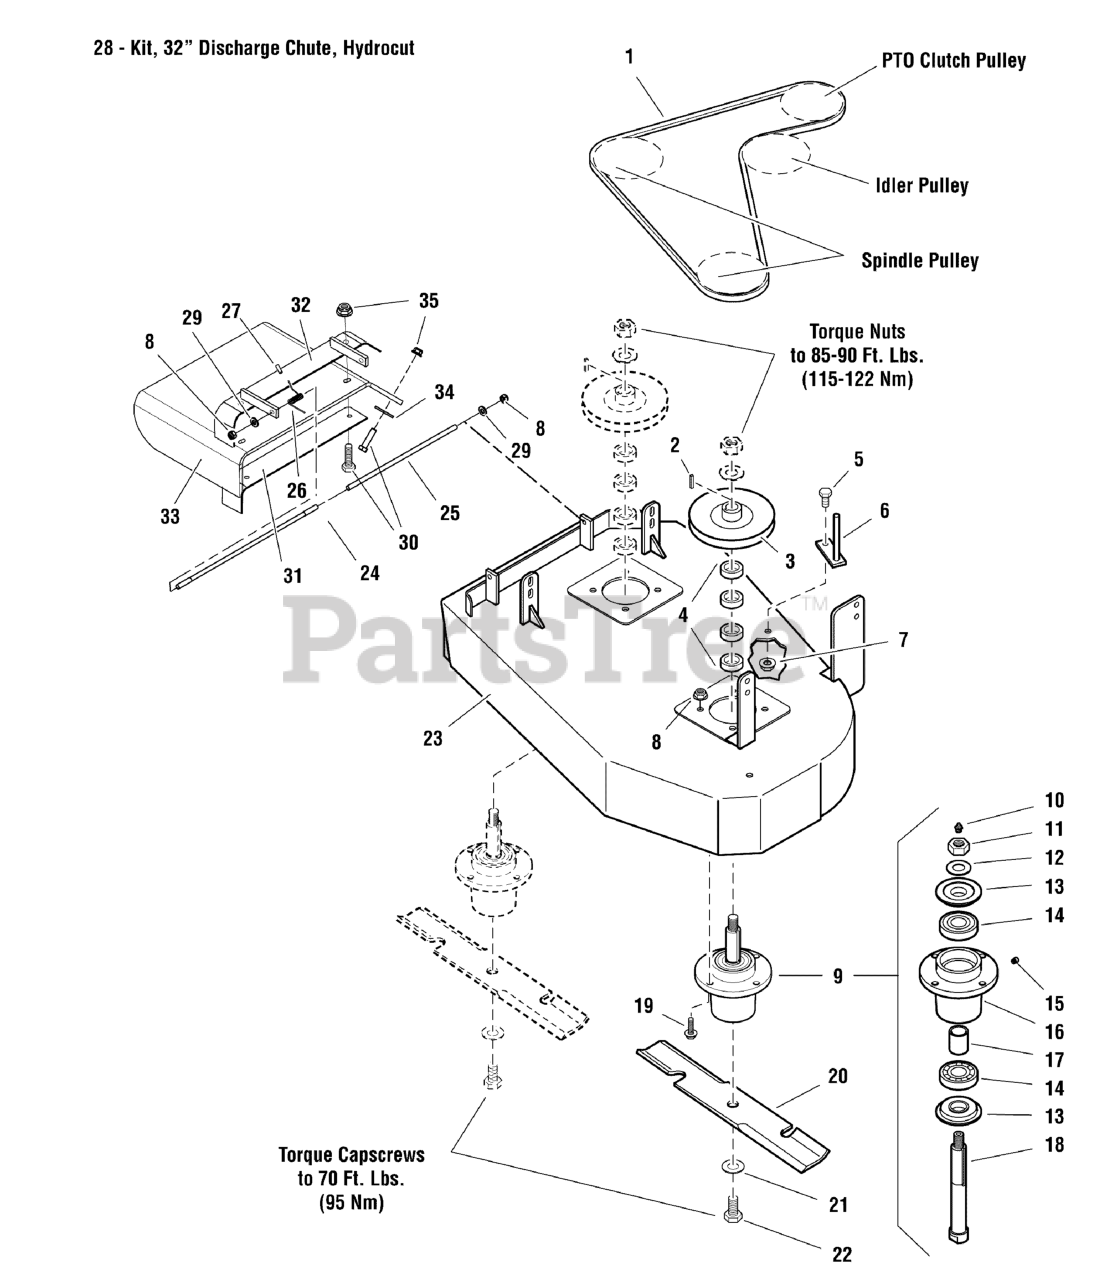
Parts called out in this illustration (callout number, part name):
1	BELT
2	KEY, 1/4 SQ. X 1
3	SPINDLE PULLEY
4	SPACER, 1.02 X 1.56 X .50
5	BOLT, 3/8-16 X 1" GD5 CZ
7	NUT, 1/4-20 HEX SERR. FLANGE
8	NUT, 5/16-18 Hex Nylock Flange
9	SPINDLE ASSM, ALUMINUM, LONG SHAFT
10	GREASE FITTING
11	NUT, 3/4-16 Hex
12	WASHER, 3/4" Belleville
13	TRASH SHIELD
14	BEARING
15	RELIEF VALVE
16	SPINDLE HOUSING
17	SPACER, 1.00 X 1.25 X 1.75
18	SPINDLE SHAFT
19	BOLT, Flange Head, 5/16-18 x 1-1/4
20	MOWER BLADE, 16-1/4"
21	WASHER, BLADE BOLT, 9/16" F436, CZ
22	BOLT, 5/8-11 x 1-3/4
23	WELD, MOWER DECK, 32" - RED
24	ROD, CHUTE PIVOT
25	TUBE, 1/2 X 3/8 X 7.50 BLACK POLY
26	SPRING, TORSION CHUTE 44/50" BLK
27	CAP, PROTECTOR, .120 ID
28	ORDER INDIVIDUAL PIECES TO SERVICE DISCHARGE CHUTE COMPONENTS
29	WASHER, 5/16" SAE
30	BOLT, 3/8-16 X 1-1/2" GD5 CZ
31	BRACKET, CHUTE SUPPORT - BLK
32	WELD, CHUTE BRACKET - RED
33	CHUTE, RUBBER, 36
34	WASHER, .390 X 1.50 X .109, YZ
35	NUT, 3/8-16 HEX NYLOCK FLANGE
